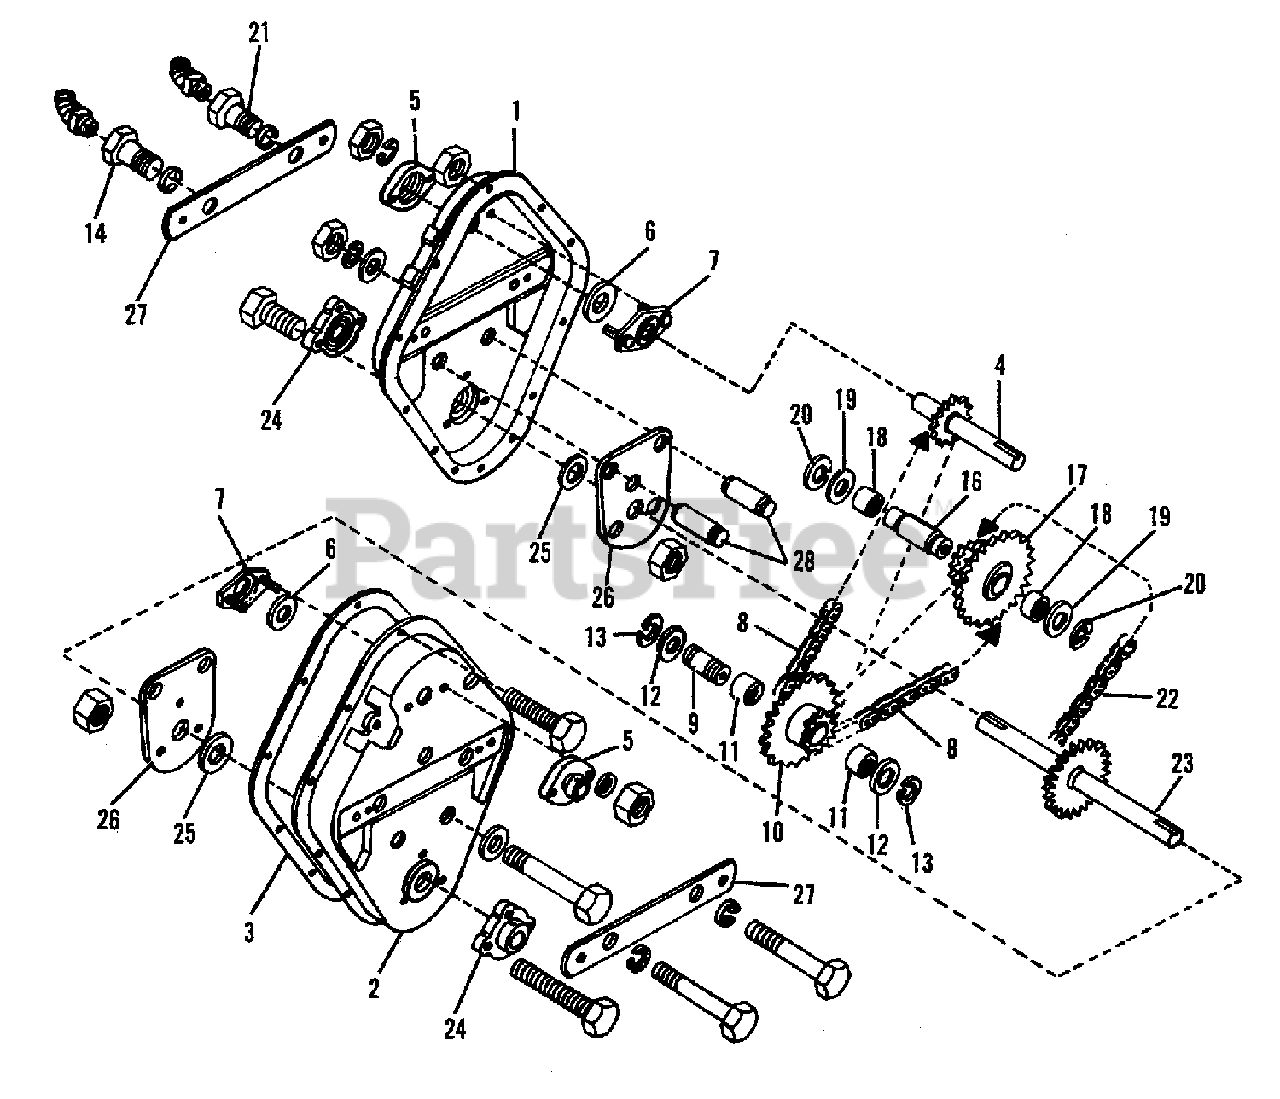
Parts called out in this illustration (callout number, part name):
1	CASE ASSEMBLY, R.H., Half
2	CASE ASSEMBLY, L.H., Half
2	CAPSCREW, 5/16NC x 5/8
2	LOCKNUT, 5/16NC
2	CAPSCREW, Hexagon, 1/2NC x 4
2	WASHER, Plain, 1/2
2	WASHER, Lock, 1/2
2	NUT, Hexagon, 1/2NC
4	SHAFT ASSEMBLY, Pulley
7	PLATE ASSEMBLY, Upper Bearing
7	WASHER, Lock, 5/16
7	NUT, 5/16NC
9	SPACER, Intermediate
10	SPROCKET ASSEMBLY
11	BEARING, Roller
13	RING, Retaining
14	BOLT, (R.H. Side)
14	FITTING, Grease
16	SPACER, Intermediate
17	SPROCKET ASSEMBLY
18	BEARING, Roller
20	RING, Retaining
21	BOLT, (R.H. Side)
21	FITTING, Grease
23	SHAFT ASSEMBLY, Tine
24	SCREW, Thread Forming, 3/8NC x 1-1/2
24	LOCKNUT, Jam, Hexagon, 3/8NC
26	PLATE, Reinforcing
27	BAR, Side, 3/16 x 2 x 13-1/16
27	CAPSCREW, Hexagon, (L.H. Side) 1/2NC x 1-1/4
27	WASHER, Lock, 1/2
28	SPACER, 1 x 7/32 x 3-1/32
